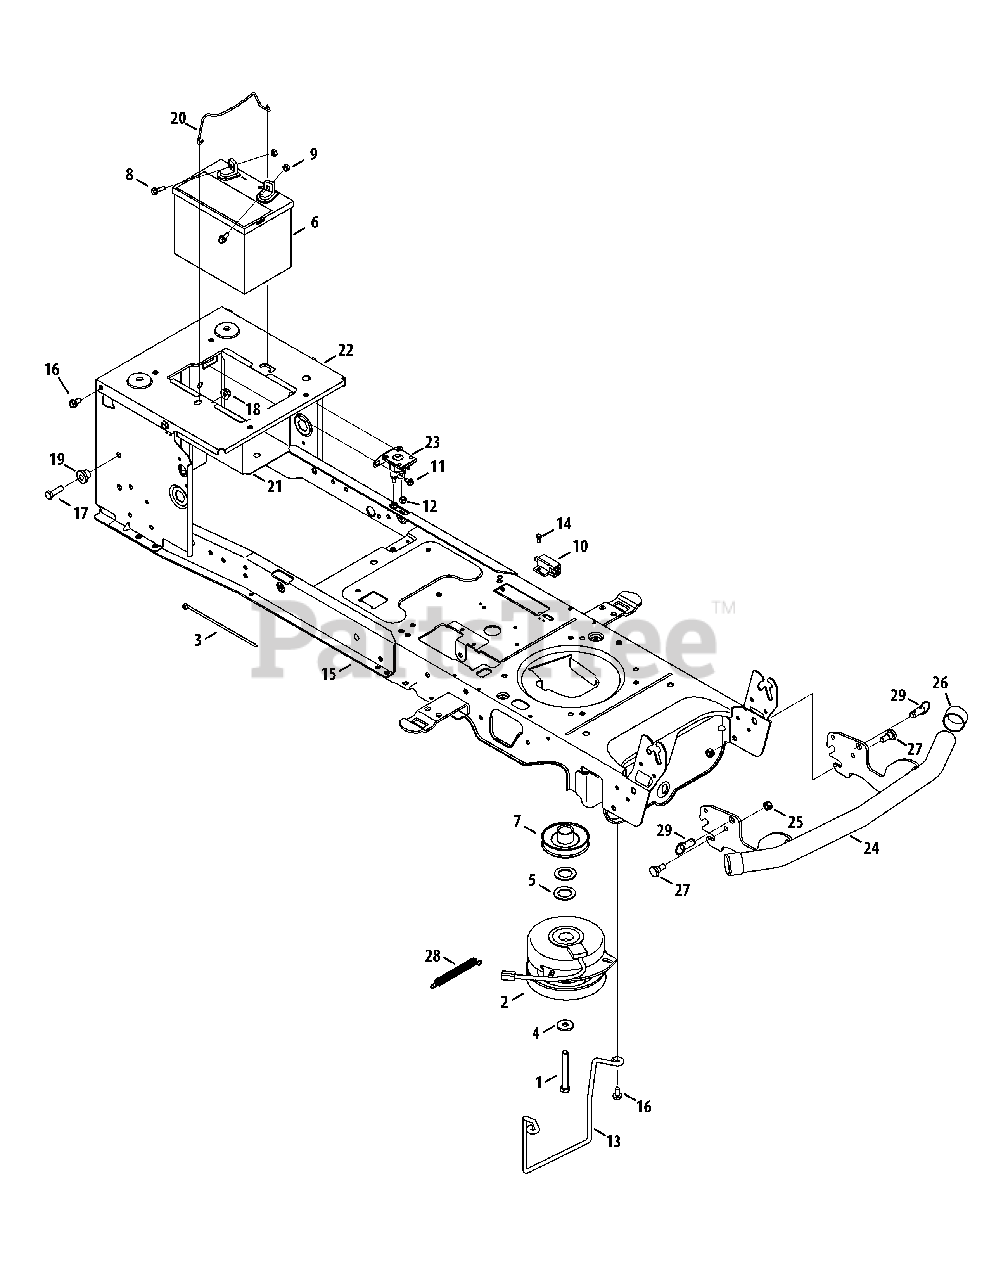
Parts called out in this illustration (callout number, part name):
1	Hex Screw, 7/16-20, 3.50, Gr5, Lock
2	Clutch, Electric PTO, 54"
2	Clutch Harness Wire 11.625"
3	Cable, Tie, 3/16 X .05 X 7.4
4	Washer, Flat, .450 x 1.25 x .164
5	Washer, Flat, 1.031 X1.620 X.095
6	Battery, 260CCA
7	Engine Pulley, Electric PTO
8	Hex Flange Screw, 1/4-20, .75, Gr5
9	Nut, Sems, 1/4-20
10	Switch, Interlock
11	Screw, Self-tapping, 1/4-20, 0.375
12	Nut, Flange Lock, 1/4-20, Nylon
13	Rod, Keeper
14	Screw, Shoulder, #10-32, .50
15	Frame Assembly, Lower
16	Screw, Self-tapping, 5/16-18, .750
17	Hex Screw, 3/8-16, 1.25, Gr5
18	Nut, Flange Lock, 3/8-16, Nylon
19	Spacer, Shoulder, .38 X 1.0 X .70
20	Rod, Battery
21	Tray, Battery
22	Bracket, Frame, Seat
23	Solenoid, 12V, 100 Amp, 4 term
24	Bumper Assembly, Universal
25	Hex Lock Nut, 3/8-16
26	Cap, Bumper
27	Bolt, Shoulder, .496 x .336, 3/8-16
28	Spr, Extn, .56 Dia X 5.52
29	Pin, Quick Release, 1/2 Dia x .50
